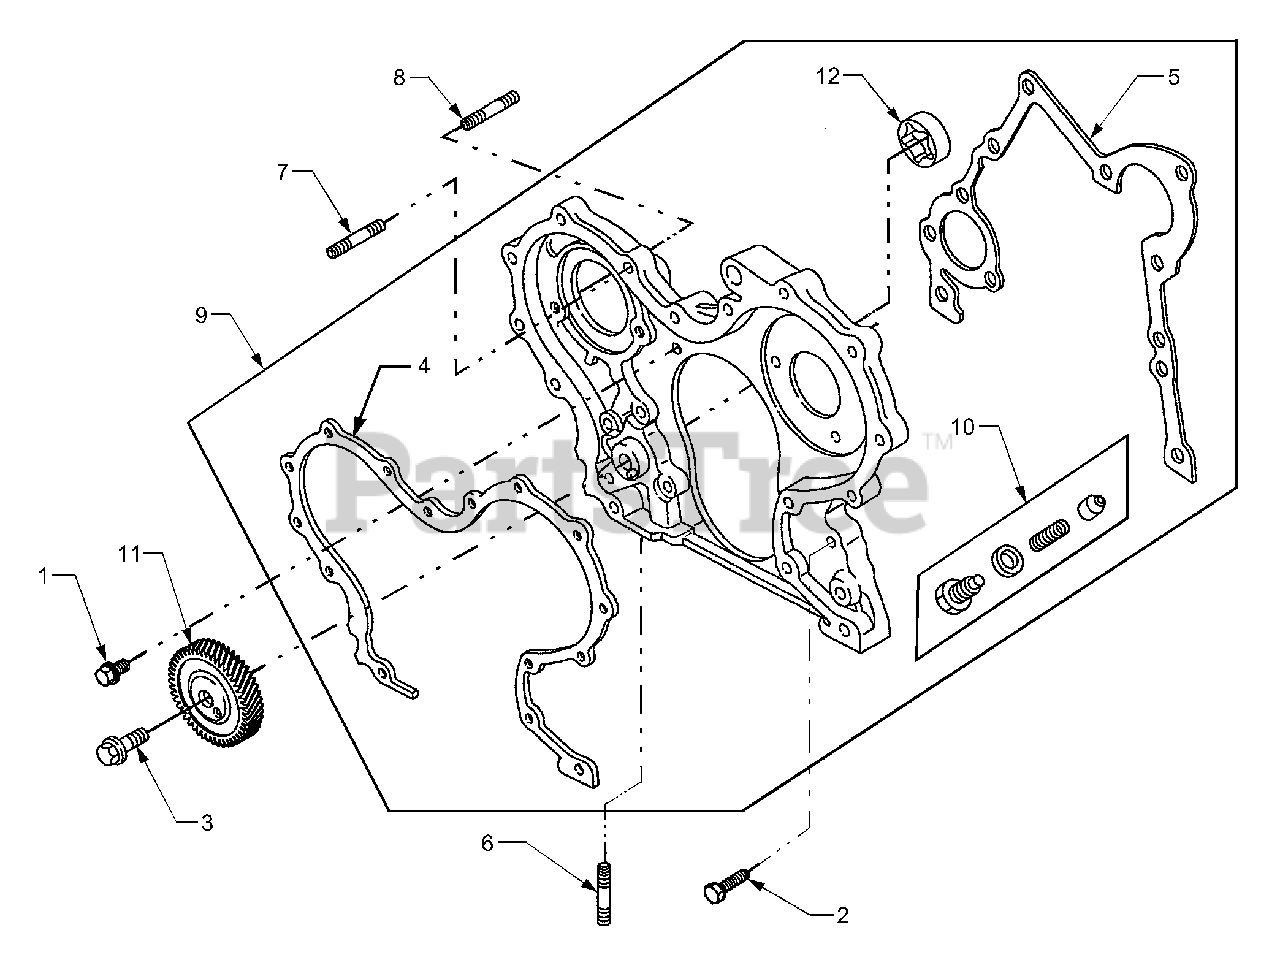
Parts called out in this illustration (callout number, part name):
1	Screw, Hex, 6mm
2	Screw, Hex, 6mm
3	Screw, Hex, 8mm
4	Gasket, Gear Cover
5	Gasket, Gear Cover
6	Stud, Metric
7	Stud, Metric
8	Stud, Metric
9	Housing, Gear
10	Valve, Oil Relief
11	Gear, Oil Pump Drive
12	Pump. Oil
